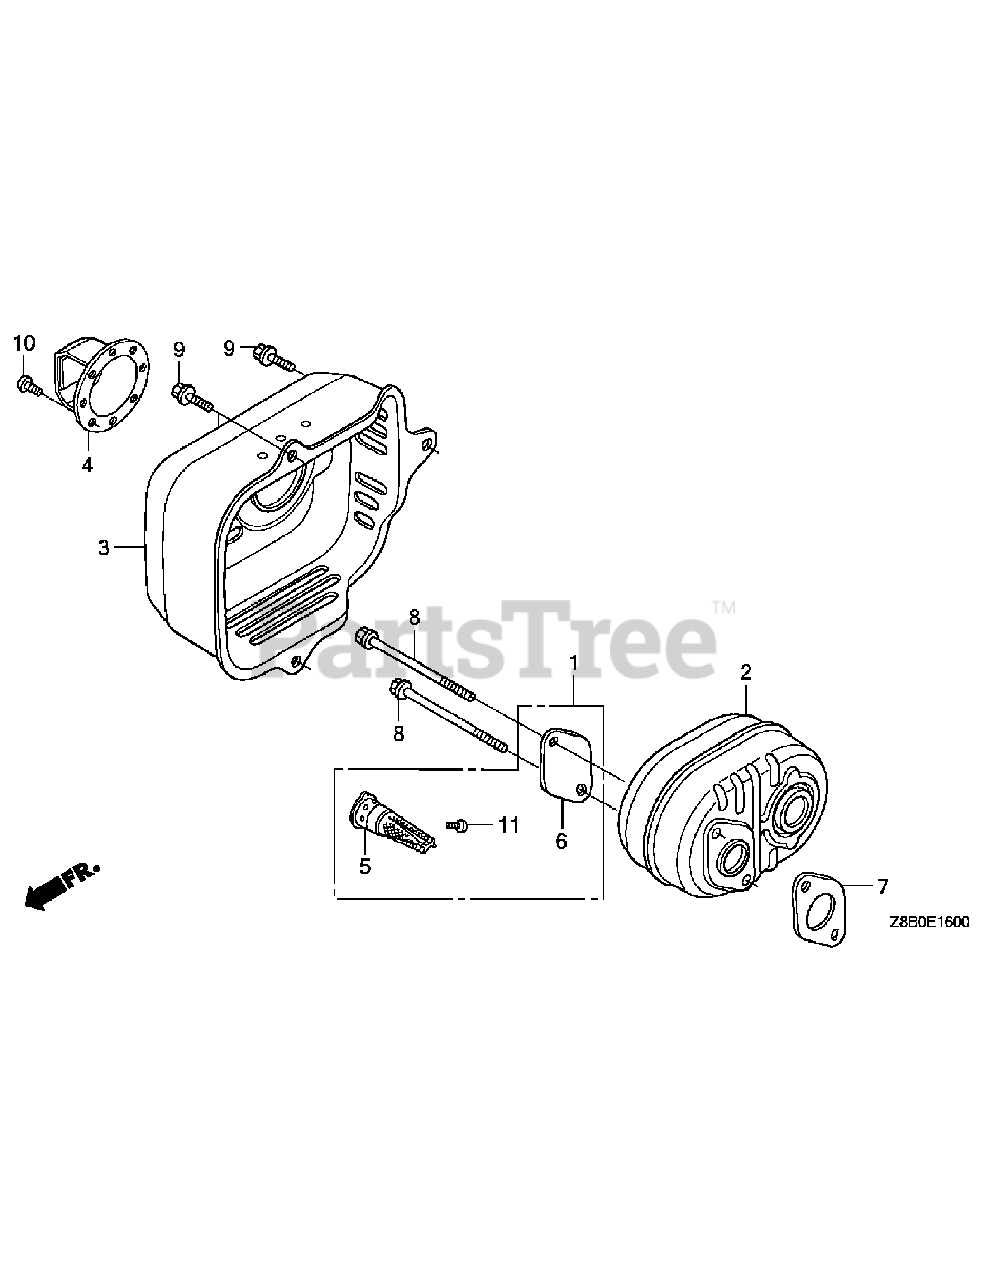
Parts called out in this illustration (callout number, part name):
1	ARRESTER KIT, SPARK
2	MUFFLER
3	PROTECTOR, MUFFLER
4	CAP, MUFFLER
5	ARRESTER, SPARK
6	PLATE, ARRESTER NUMBER
7	GASKET, MUFFLER
8	BOLT, FLANGE (6X79) (CT200)
9	BOLT, FLANGE (6X12) (CT200)
10	SCREW, TAPPING (4X6)
11	SCREW, TAPPING (4X6)
